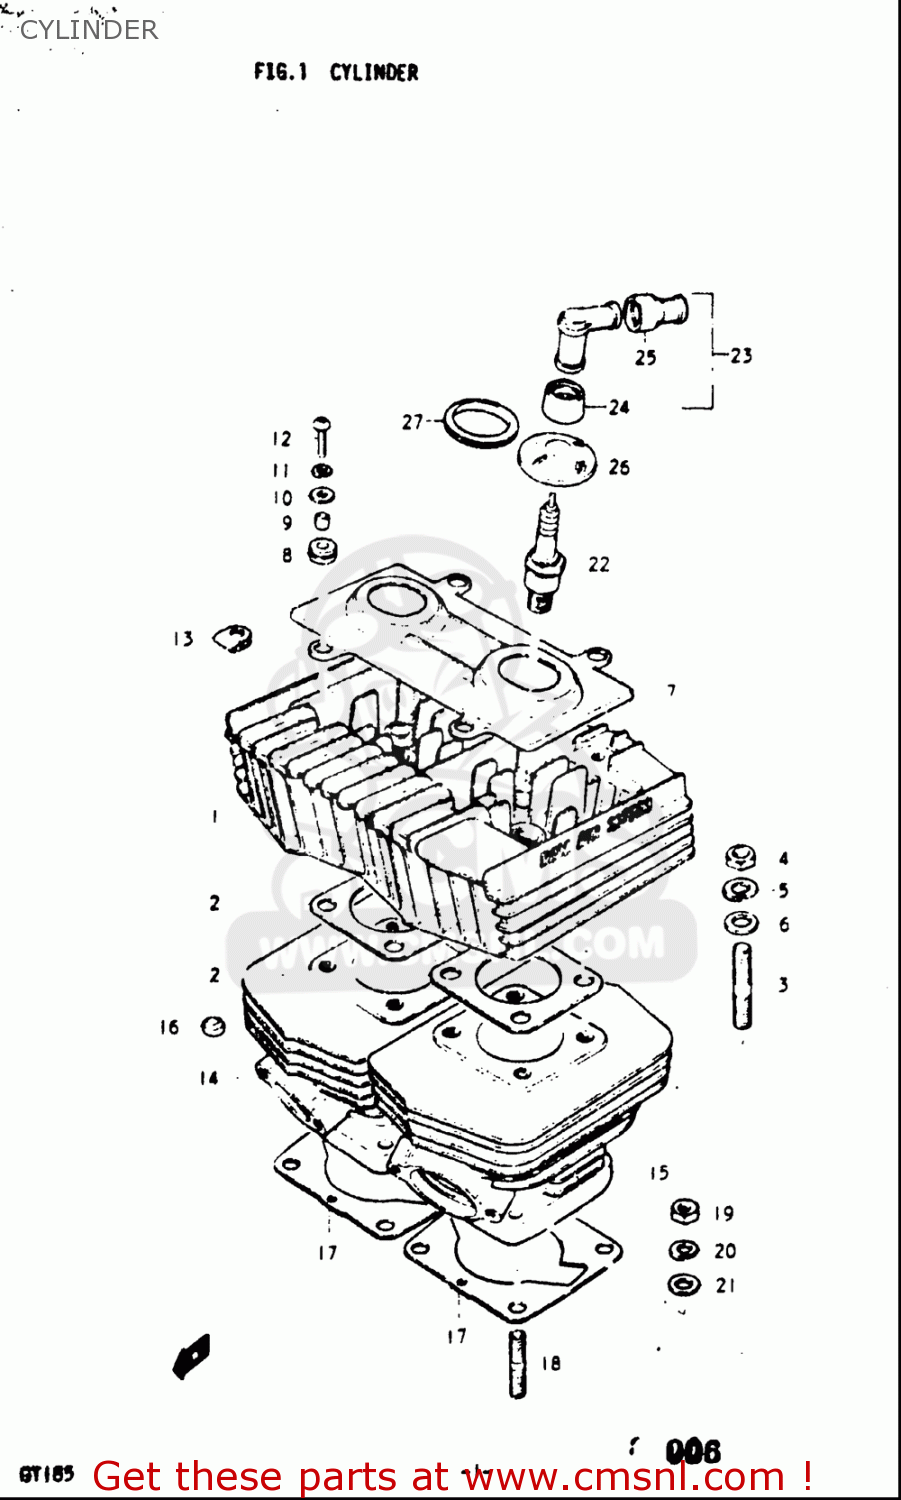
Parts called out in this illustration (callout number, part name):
2	GASKET,CYLINDER HEAD (NAS)
3	STUD 10X30
4	NUT
5	WASHER,LOCK
6	WASHER
8	CUSHION
9	SPACER(6.2X8.3X5.7)
10	WASHER(6.5X14X1.6)
11	WASHER,LOCK
12	SCREW
17	GASKET,CYLINDER (NAS)
18	STUD 8X25
19	NUT
20	WASHER,LOCK
21	WASHER
22	PLUG,SPARK(B7HS)
23	CAP,SPARK PLUG
24	SEAL,SPARK PLUG
25	SEAL,HIGH TENSION CORD
27	GROMMET
